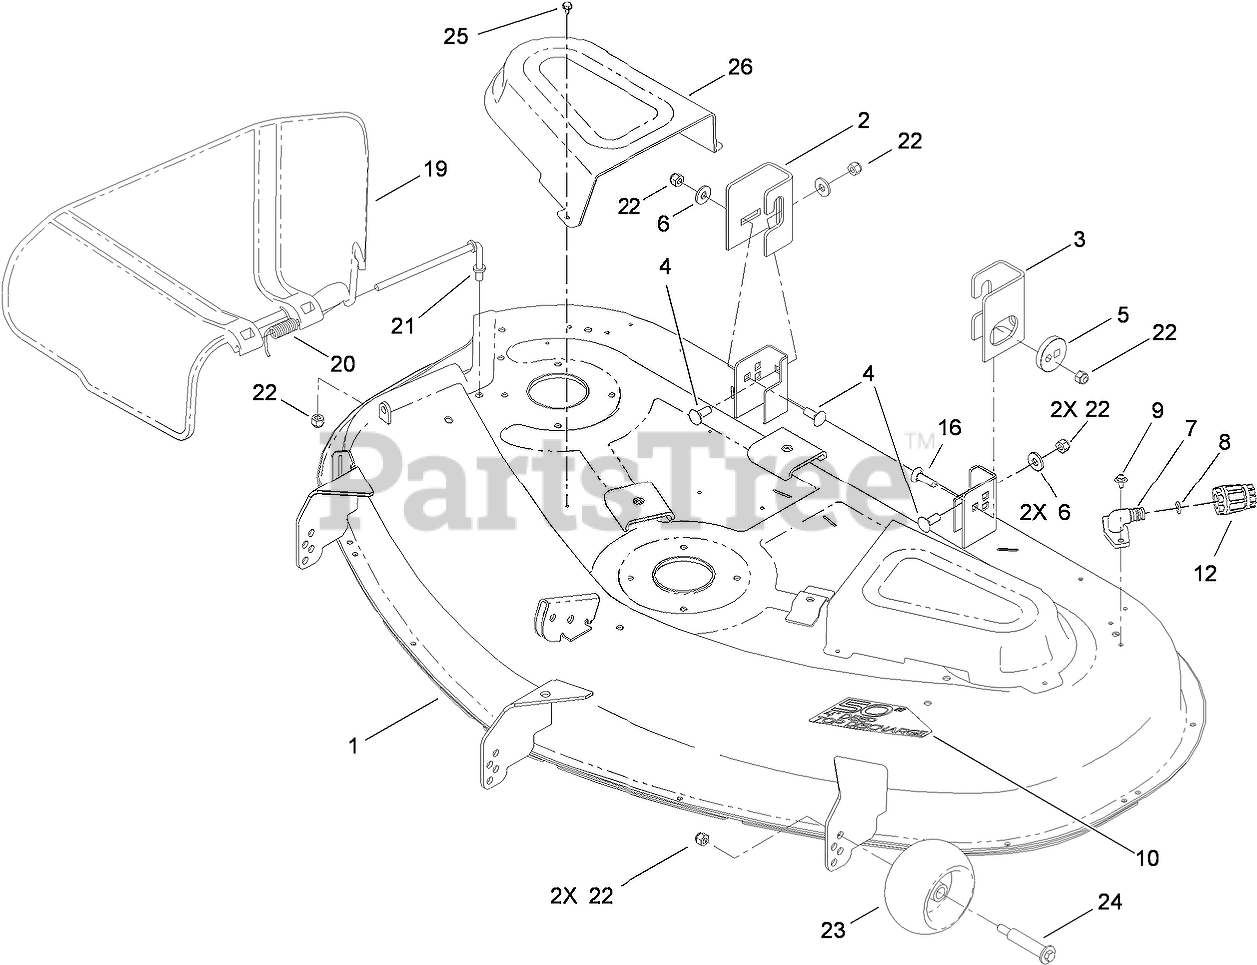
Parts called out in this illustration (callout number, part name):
1	50 INCH DECK ASM
2	BRACKET-HANGER, RIGHT REAR
3	BRACKET-HANGER, LEFT REAR
4	BOLT-CARR
5	ECCENTRIC
6	WASHER-HARDENED
7	FITTING-WASHOUT
8	O-RING
9	SCREW-HHFTF
12	CONNECTOR-HOSE
16	SCREW-CARR
19	DEFLECTOR
20	SPRING-TORSION
21	ROD-PIVOT
22	NUT-LOCK, NI
23	ROLLER-SCALP, ANTI
24	BOLT-SHOULDER
25	SCREW-HWHTF
26	COVER-BELT
